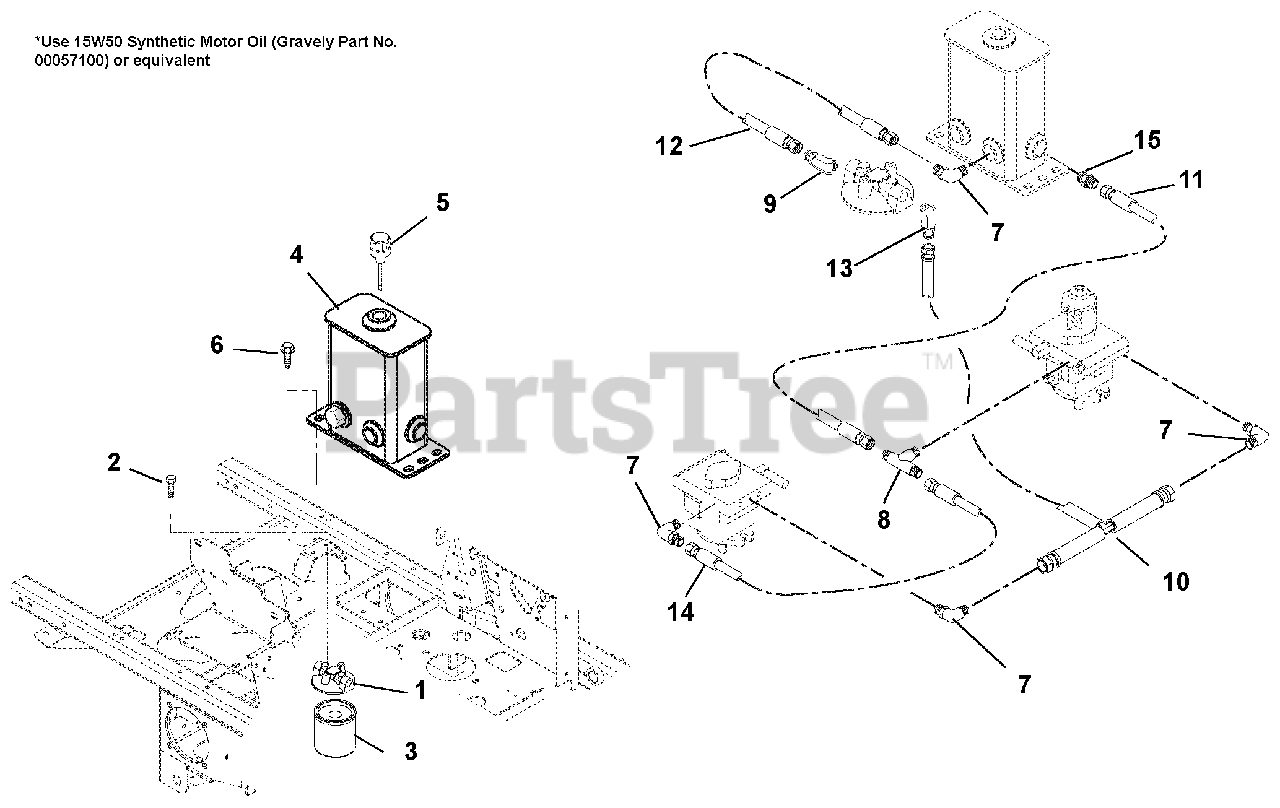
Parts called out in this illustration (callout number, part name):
1	Head, Filter
2	Bolt, Hex .25-20 x .50 Epoxy Grade 5
3	Oil Filter with Bypass
4	Weldment, Formed Hydraulic Tank – 2 Port
5	Dipstick, Breather
6	Screw, Tapping Hex Washer Head .38-16 x .75
7	Fitting, Hydraulic, 90 Degree Elbow, Steel M8F – M80
8	Fitting, Hydraulic Tee M80 – M80 – M80
9	Fitting, Hydraulic Straight M80 – M80
10	Hose, Tee Assembly, .50
11	Hose, Hydraulic .50-19 – 0K FO8J0 – FO8J0
12	Hose, Hydraulic Molded
13	Fitting, Hydraulic 45° M80 – M80
14	Hose, Hydraulic
15	Adapter, Face Seal 8 x 8 .50 O-Ring 8 F5OLO – Steel
